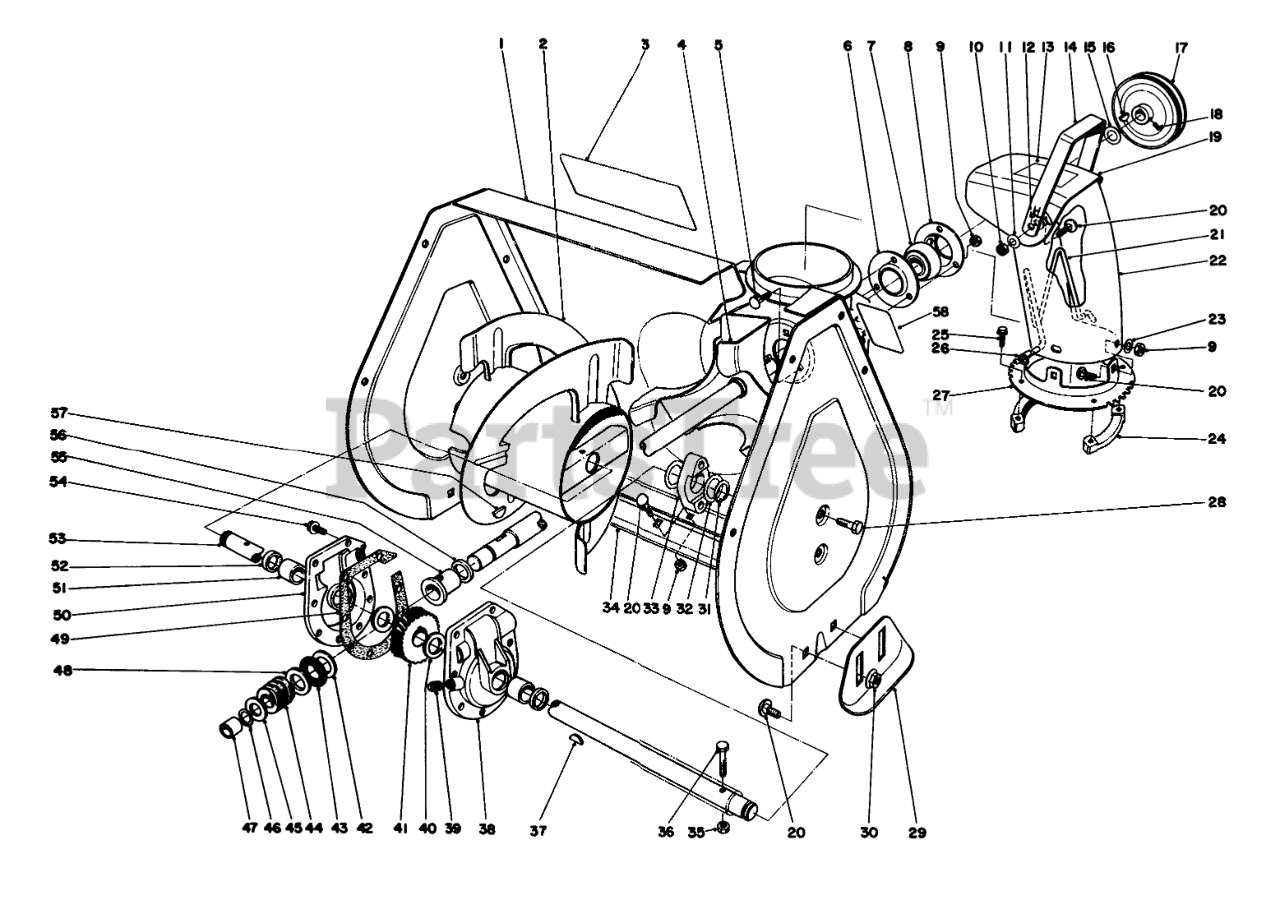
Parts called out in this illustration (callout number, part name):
1	Auger Housing
2	Auger R.H.
3	AUGER WARNING DECAL
4	Shaft & Impeiler
5	BOLT-CARR
6	FLANGE-CUP, BEARING
7	Ball Bearing
8	FLANGE-CUP, BEARING
9	NUT-LOCK, NI
10	NUT-LOCK, CONE
11	WASHER-BELLEVILLE
12	WASHER-RUBBER
13	Decal-Danger
14	Handle Deflector
15	WASHER
16	KEY-WOODRUFF
17	PULLEY
18	SCREW-SET, SQH
19	Deflector (Incl. Ref. #13)
20	BOLT-CARR
21	CHUTE WIRE
22	DISCHARGE CHUTE
23	WASHER-PLAIN
24	RING-CHUTE, RETAINER
25	SCREW-SPECIAL
26	NUT-PUSH
27	Chute Ring
28	SCREW-HWHTF
29	Skid
30	NUT-HF
31	RING-RETAINING
32	WASHER
33	BEARING-AUGER
34	Blade-Scraper
35	NUT-LOCK, CONE
36	SCREW-HH
37	KEY-WOODRUFF
38	Gear Case L.H. (Incl. Ref. #51 & 52)
39	PLUG-PIPE, SQH
40	WASHER-THRUST
41	Gear
42	WASHER-THRUST
43	BEARING-THRUST
45	WASHER-THRUST
46	Ring-Snap
47	BUSHING
48	WASHER-THRUST
49	GASKET-CASE, GEAR
50	Gear Case R.H. (Incl. Ref. #51 & 52)
51	BUSHING
52	SEAL-OIL
53	AUGER SHAFT
54	SCREW-TAPTITE
55	BUSHING-INPUT
56	RING-QUAD
57	KEY-WOODRUFF
58	DECAL-WARNING, AUGER
